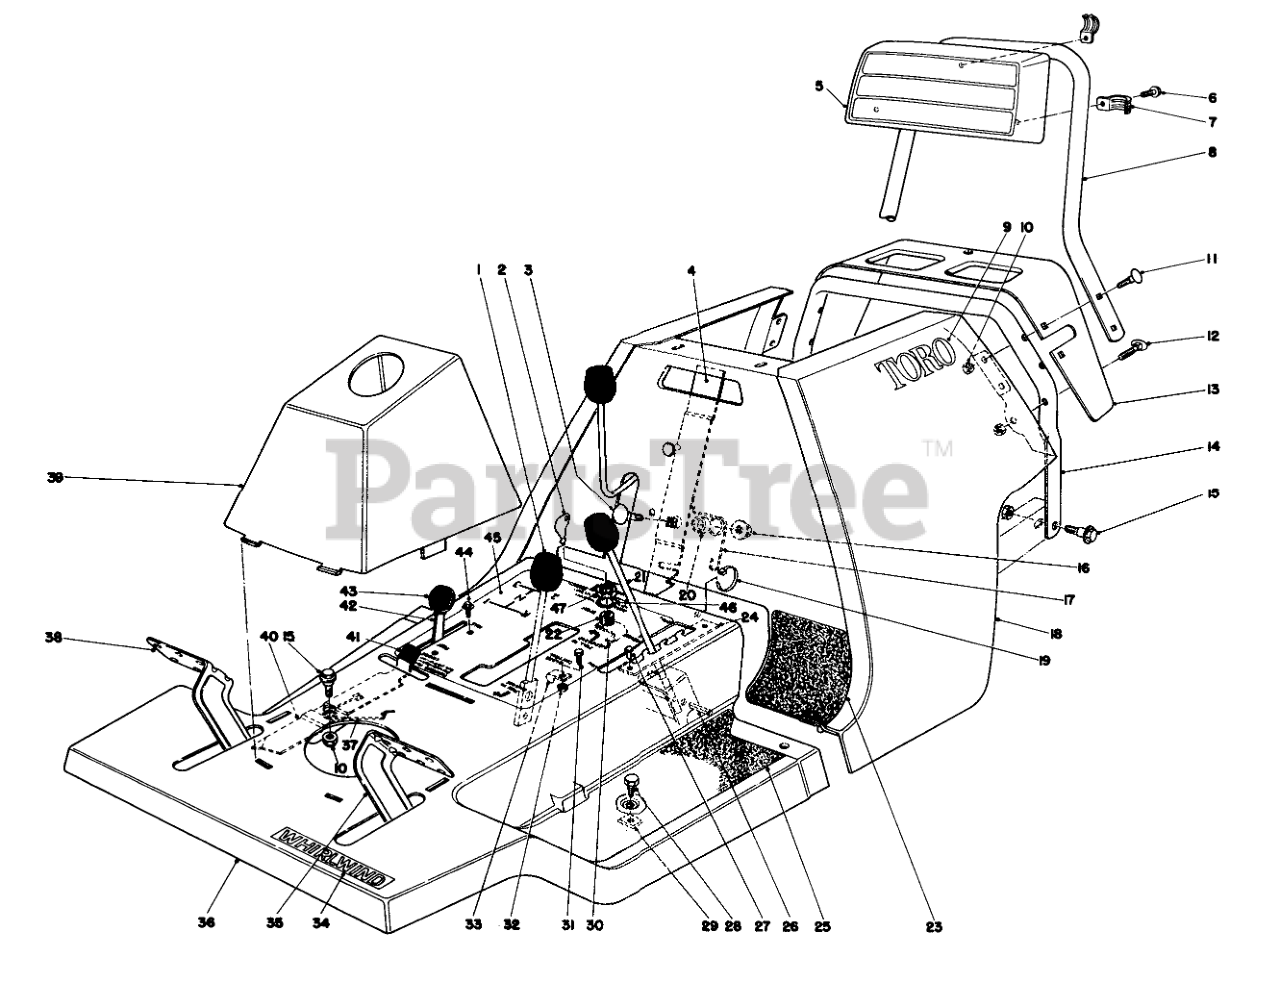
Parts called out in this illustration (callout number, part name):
2	Key
2	Rear Support Seat
3	BOLT-CARR
3	WASHER-FLAT
4	Handle Latch
4	WASHER-LOCK
5	Backrest
5	SCREW-HH
6	Screw
6	NUT-LOCK, CONE
7	Clamp Conduit
7	SEAT SWITCH
8	Handle Upper
8	Spring
9	Decal
9	SCREW-HH
10	NUT-LOCK, CONE
10	Seat Support-Rear Lower
11	SCREW-CARR
11	SCREW-SHOULDER
12	HANDLE SCREW
12	Seat Pivot Bracket Lower
13	Extension Rear Body
13	Seat Pivot Bracket Upper
14	Handle Lower
14	TIE-CABLE
15	SCREW-SHOULDER
16	NUT-HF
17	Latch Return Spring
18	Rear Body
19	TIE-CABLE
20	Spacer
21	Height of Cut Lever
22	Starter Switch (Incl. Ref. #2, 45 & 46)
23	Heel Pad-LH.
24	Height Adjustment Plate
25	Foot Tread LH.
26	PIN-SPECIAL
28	SCREW-HH
29	NUT-TINNERMAN
32	NUT-KEPS
33	CABLE CLAMP
34	WW DECAL
35	Clutch Pedal
36	Body-Front (Incl. Ref. #24, 27 & 47)
37	SPRING-PARKING BRAKE
38	Brake Pedal
39	Tower
40	Parking Brake
41	TIP-PARKING BRAKE
42	Throttle Control (Incl. Ref. #43)
44	8X1/2 SELF TAP SCREW
45	Decal-Front Body
46	WASHER-TOOTH, INTERNAL
47	NUT-HH
